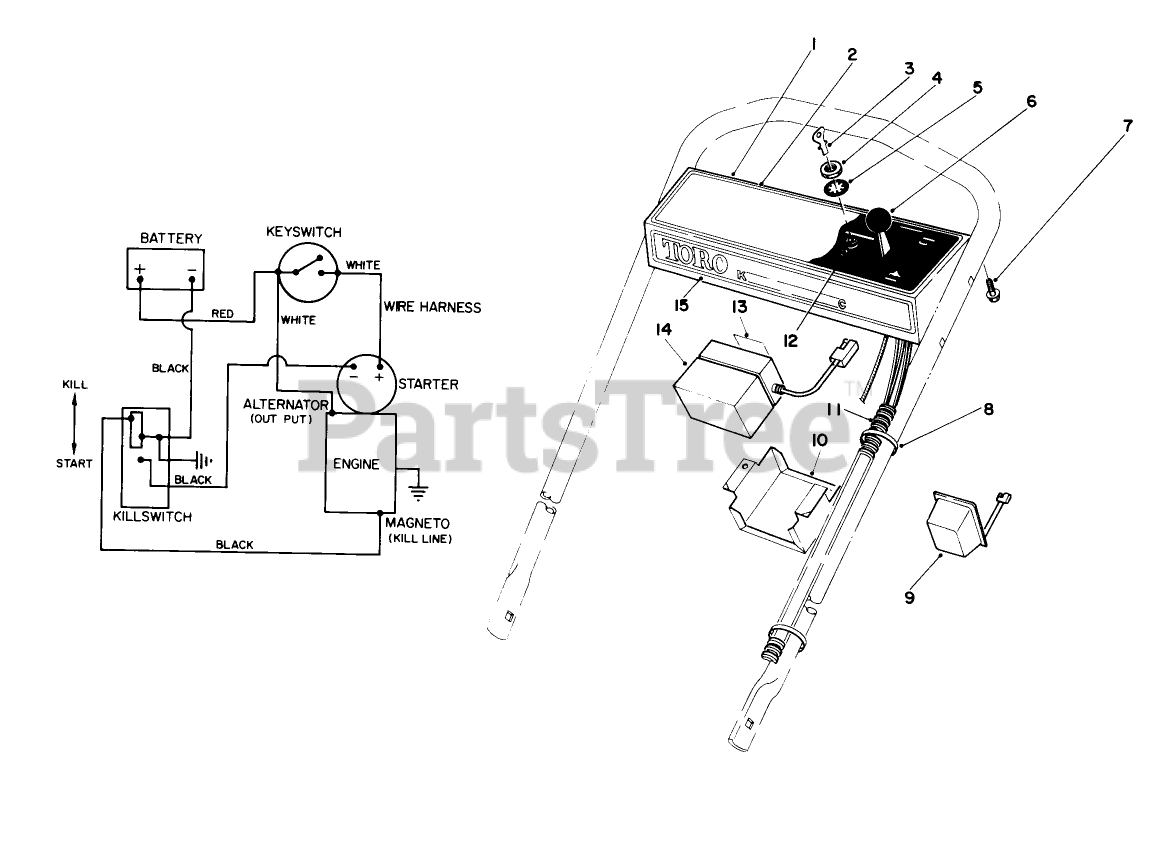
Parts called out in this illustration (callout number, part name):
4	NUT-HH
5	WASHER-LOCK
6	SERVICE THROTTLE CONTRO
7	SCREW-HWHTF
8	TIE-CABLE
10	Retainer-Battery
11	WIRE HARNESS
12	STARTER SWITCH ASM
13	Decal
